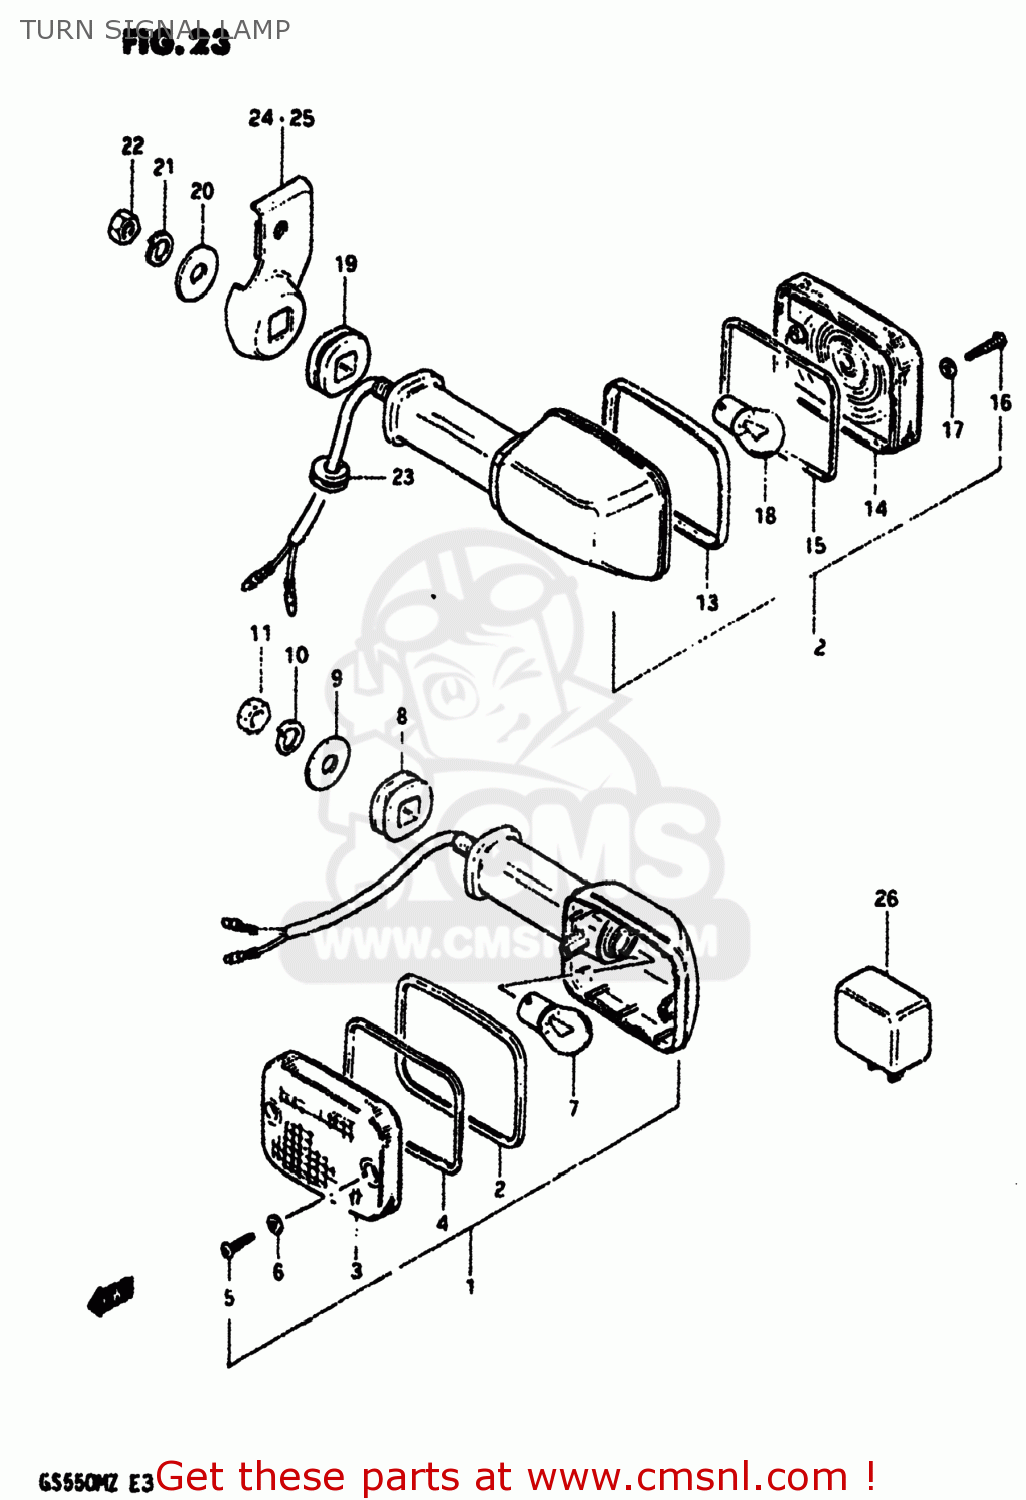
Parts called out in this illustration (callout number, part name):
1	LAMP ASSEMBLY,FRONT TURN SIGNAL
2	RIM
3	LENS
4	GASKET (NAS)
5	SCREW
6	GASKET (NAS)
7	BULB(12V23W,STANLEY,A4577A)
8	CUSHION
9	WASHER (10.5X30X2.3)
10	LOCK WASHER
11	NUT
12	LAMP ASSEMBLY,FRONT TURN SIGNAL
13	RIM
14	LENS
15	GASKET (NAS)
16	SCREW
17	GASKET (NAS)
18	BULB(12V23W,STANLEY,A4577A)
19	CUSHION
20	WASHER (10.5X30X2.3)
21	LOCK WASHER
22	NUT
23	GROMMET
24	BRACKET,REAR TURN SIGNAL
25	BRACKET,REAR TURN SIGNAL
26	RELAY,TURN SIGNAL
